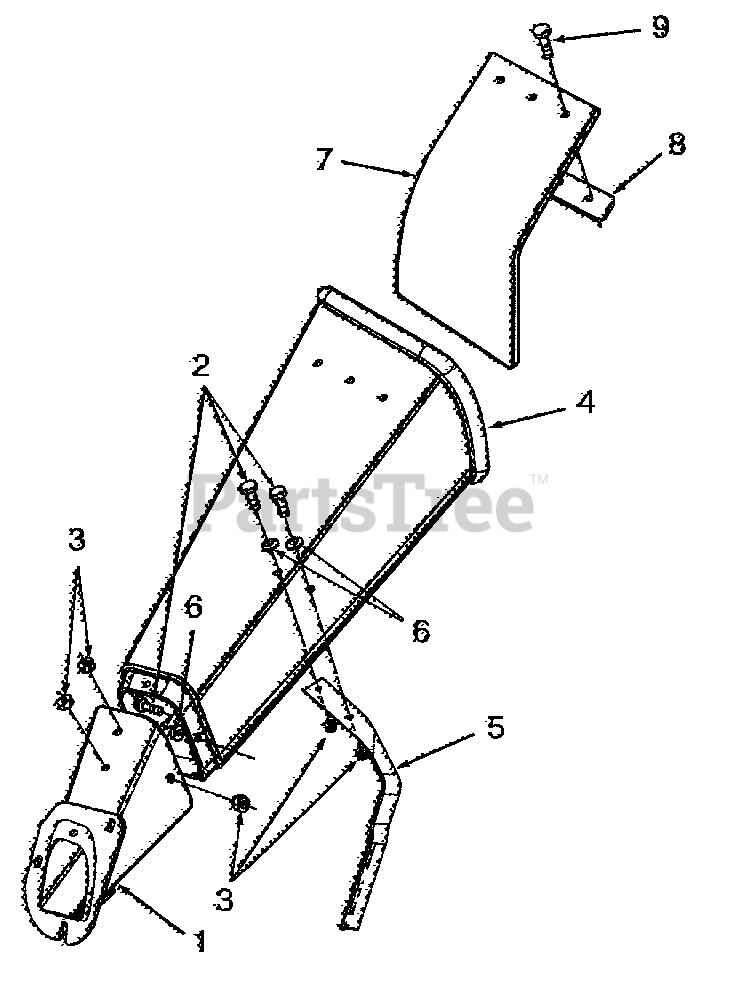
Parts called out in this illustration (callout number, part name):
1	Chute Assembly, Chipper
2	Screw, Hex Cap, 1/4-20 x .625
3	Nut, Hex Flange Lock, 1/4-20
4	Chute, Chipper
5	Bracket, Chipper Chute Support
6	Washer, Flat, .28 x .74 x .63
7	Flap, Chipper Chute
8	Strip, Chute Flap
9	Rivet, Pop, .156 x .504
